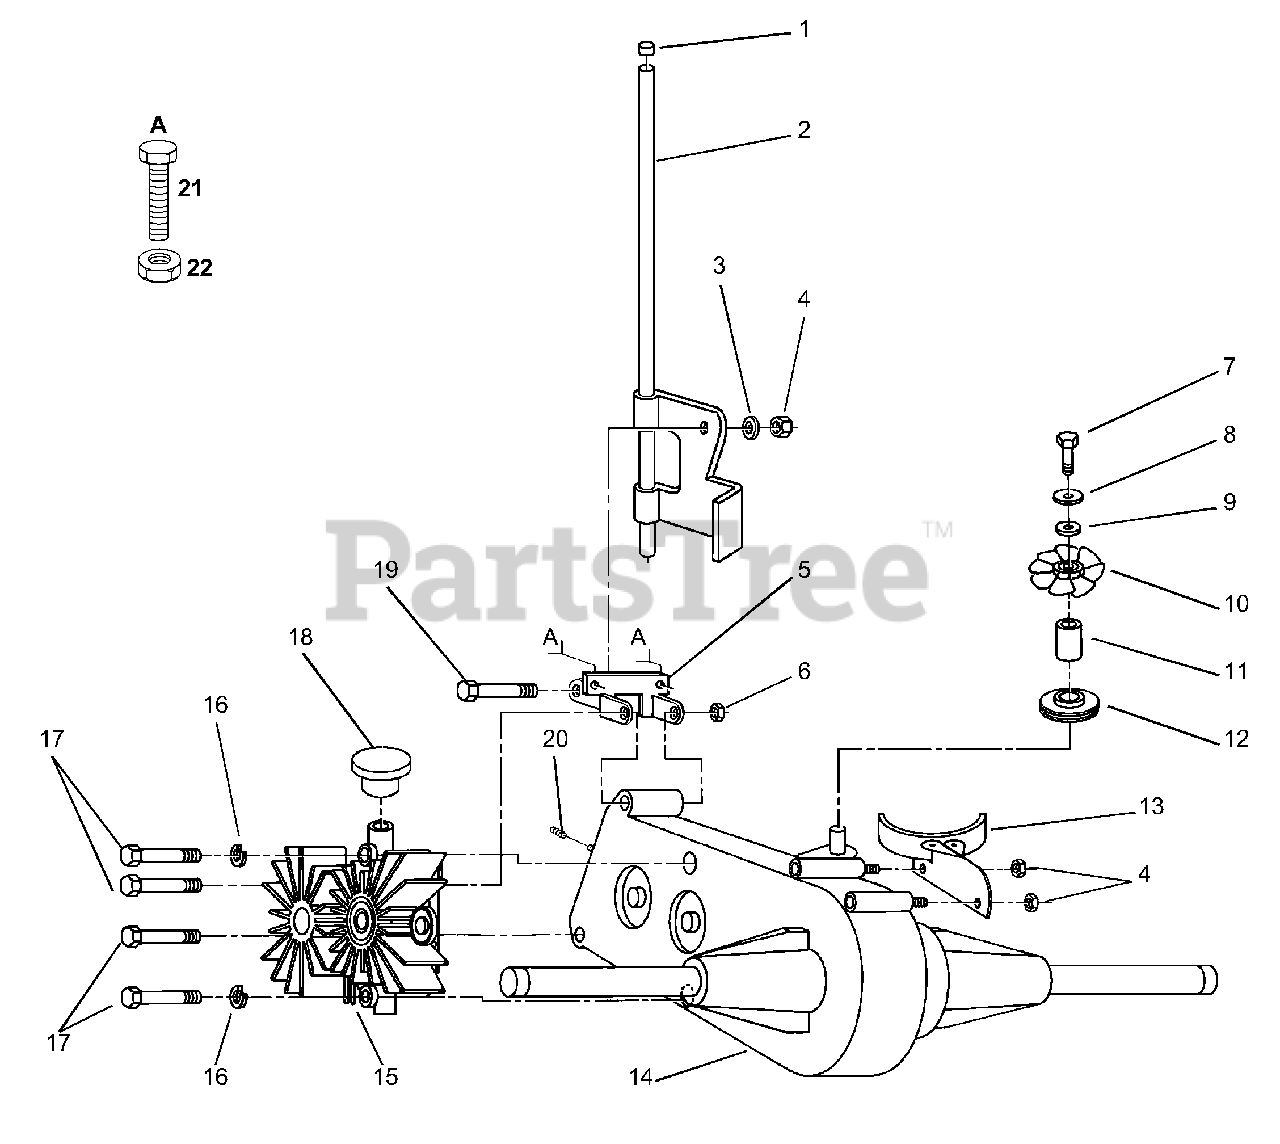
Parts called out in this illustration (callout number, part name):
1	Cap, Plunger
2	Rod, Free Wheel Control Assembly
3	Washer, Nylon
4	Nut, Crownlock 1/4 - 20 UNC
5	Bracket, Painted, Mounting, Differential
6	Nut, Crownlock 5/16 - 18
7	Bolt, Hex 1/4 - 20 UNC x 3/4
8	Washer
9	Washer 9/32 x 1-1/4 x 16 Gauge
10	Fan, Hydro, 8"
11	Standoff, Fan, Hydro
12	Pulley, Transaxle
13	Guard Assembly, Belt
14	Differential Assembly
15	Pump Assembly
16	Washer Lock
17	Bolt, Hex Fin. 5/16 - 18 UNC x 4 1/2
18	Reservoir, Pump
19	Bolt, Shoulder 1/4 - 20 UNC
20	Spring, Compression
21	Bolt 3/8 - 16 x 3/4
22	Nut 3/8 - 16 UNC
